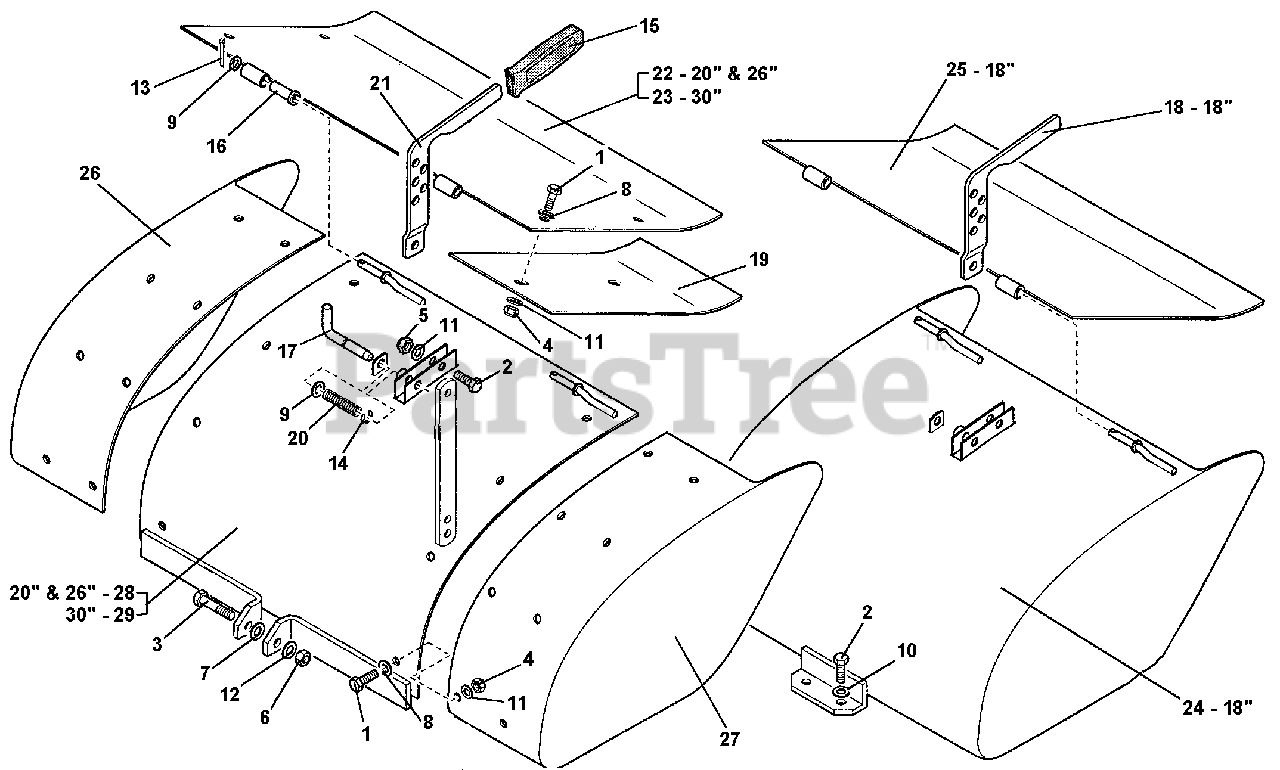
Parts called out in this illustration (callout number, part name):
1	SCREW, M8X16
2	SCREW, M8X25
3	SCREW, M12X85
5	NUT, SELF LOCKING, M8
7	FLAT WASHER
8	WASHER, FLAT, M8.4
10	WASHER, M8.4
11	WASHER, LOCK, M8.4
12	WASHER, LOCK, M13
17	ADJUSTMENT PIN
21	DEPTH ADJUSTMENT LEVER
22	CENTER FLAP, 20" & 26" TILLER
23	CENTER FLAP 30" TILLER
24	TILLER HOOD, 18" TILLER
25	CENTER FLAP, 18" TILLER
26	RIGHT SIDE FENDER, 20" -30" TILLER
27	LEFT SIDE FENDER, 20" - 30" TILLER
28	TILLER HOOD, 20" & 26" TILLER
29	CENTER HOOD 30" TILLER
